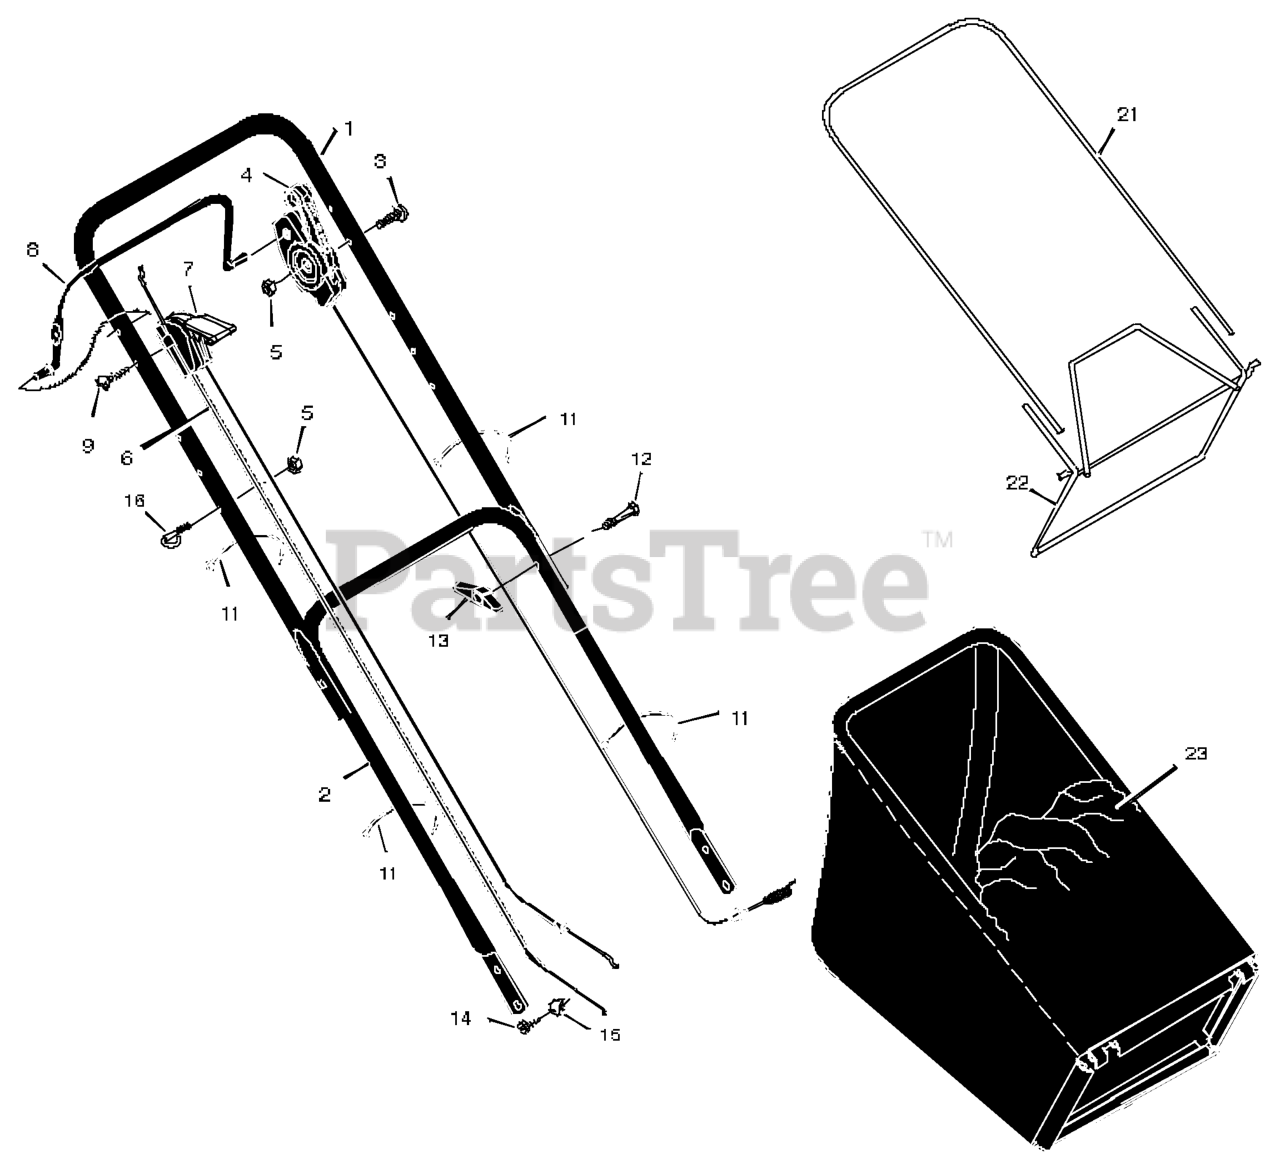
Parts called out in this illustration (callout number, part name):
1	Handle, Upper (Gray)
2	Handle, Lower (Gray)
4	Control, Drive
5	Locknut
6	Cable, Stop
7	Throttle Control
8	Engine Stop Lever
11	Fastener, Cable
13	Knob
16	GUIDE, ROPE
21	Frame, Top
22	Frame Assembly
23	Bag, Cloth
